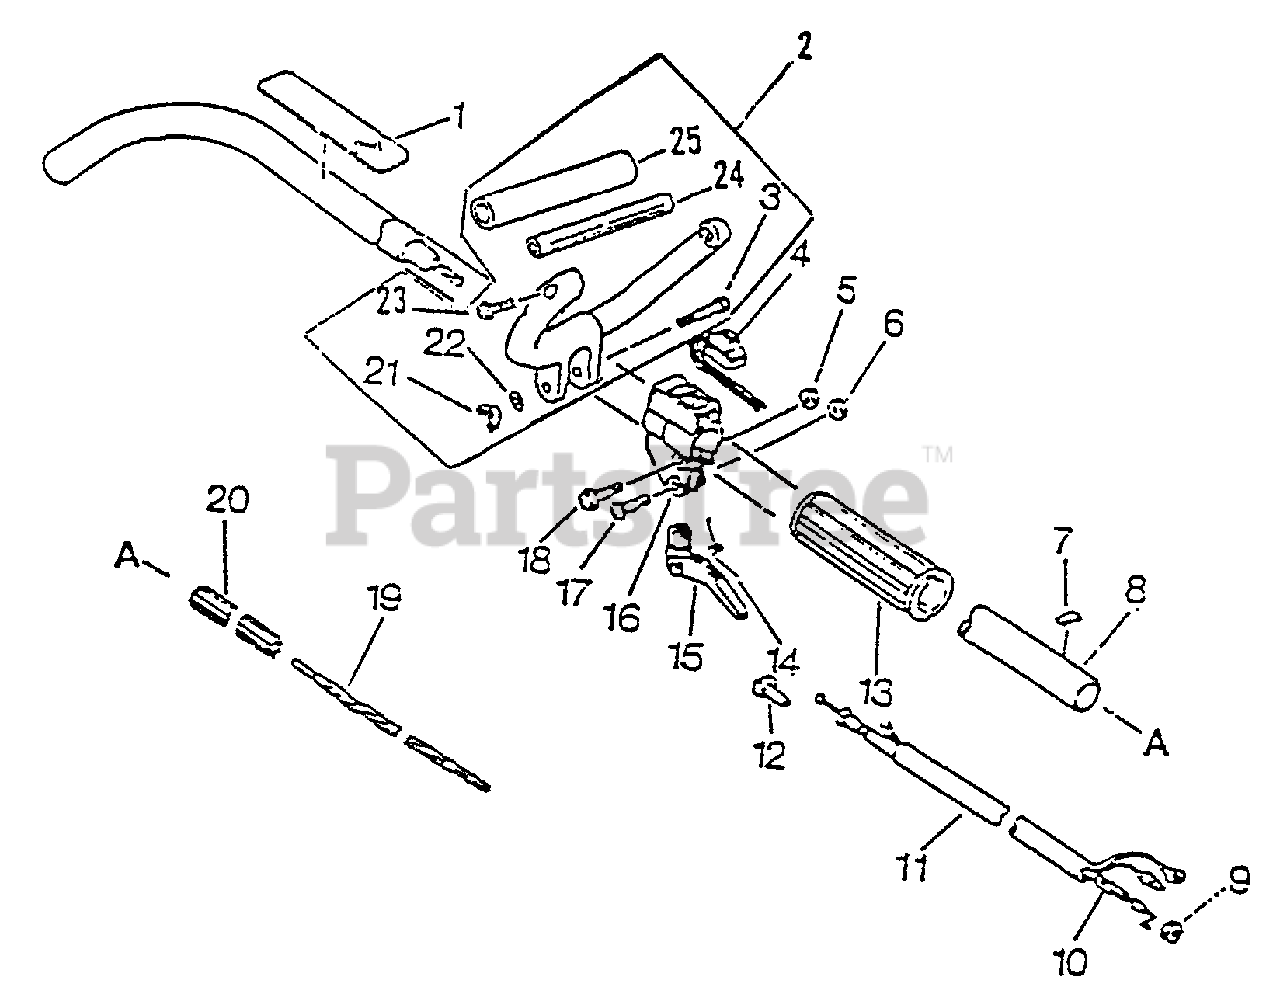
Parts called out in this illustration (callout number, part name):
1	LABEL - CAUTION
2	LOOP HANDLE ASSY
3	BOLT - 6X40
4	IGNITION SWITCH ASSY
6	LOCKNUT - 5
7	LABEL - ALIGNMENT
8	PIPE, MAIN
10	CABLE, THROTTLE
11	TUBE - VINYL
12	GUIDE, CABLE
13	GRIP, HANDLE
14	SPRING, TRIGGER
15	TRIGGER, THROTTLE
16	BRACKET, THROTTLE CONTROL
17	SCREW - 5X30
18	SCREW - 5X28
19	DRIVESHAFT - FLEXIBLE
20	LINER - FLEXIBLE
21	WINGNUT - 6
22	WASHER - 6
23	SCREW - 5X30
24	HANDLE
25	GRIP, HANDLE
